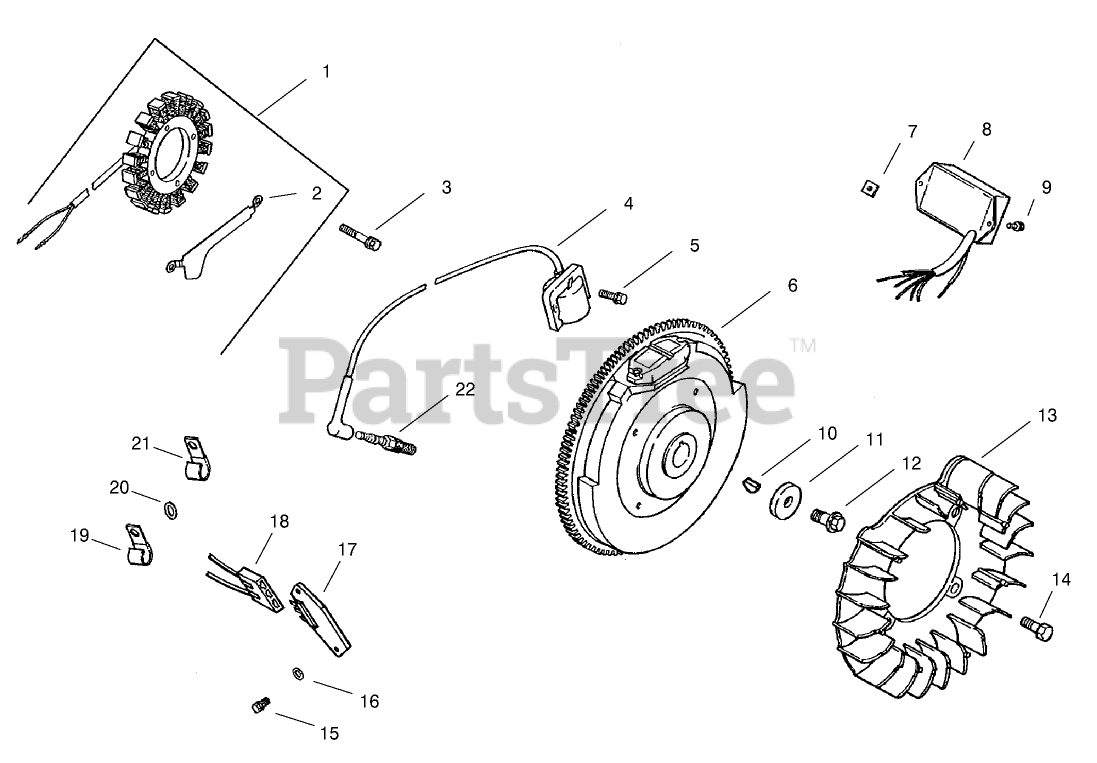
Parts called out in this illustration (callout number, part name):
1	Kit-Stator, 15 amp (Incl. 2)
2	Bracket-Wire, Stator
3	SCREW-THREAD FORMING (M5X0.8X25)
4	Module-Ignition
5	Screw-Socket, Hex (M5x0.8x25)
6	Flywheel
7	NUT-PLASTIC
8	Module-Advance, Speed
9	SCREW-PPH (11-16X1/2)
10	KEY (3/16 X 5/8)
11	WASHER-FLAT (13/32)
12	SCREW-FLANGE (M10X1.5X45)
13	Fan
14	BOLT-SHOULDER (M6x1.0x16)
15	SCREW-PHL HD (11-16X.88)
16	WASHER-FLAT (.188)
17	Rectifier-Regulator, 15 amp
18	Connector (3 contact)
19	CLIP-CABLE
20	WASHER-FLAT (1/4)
21	Clip-Cable
22	Spark Plug
